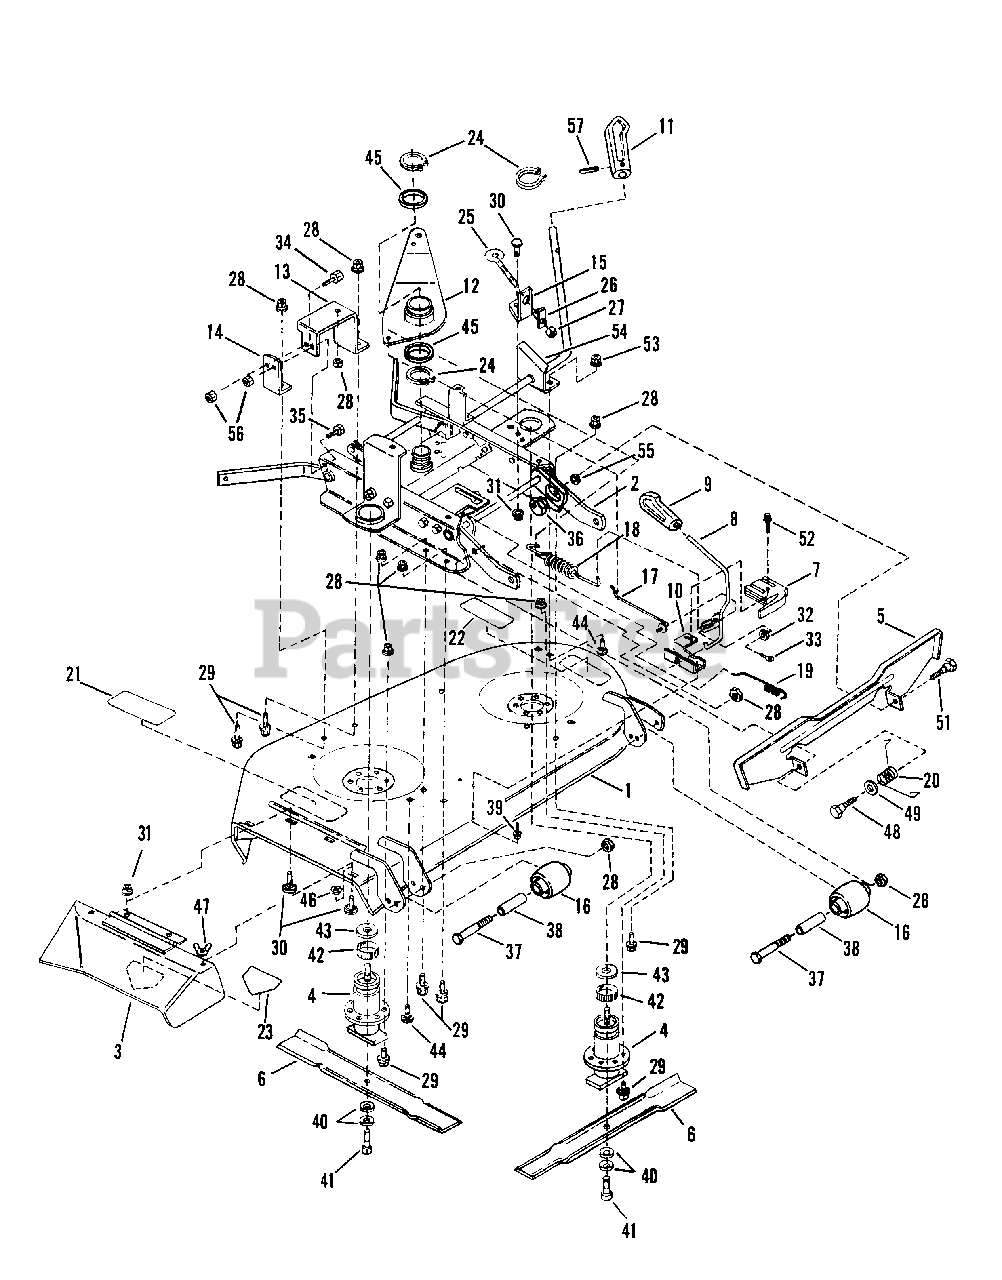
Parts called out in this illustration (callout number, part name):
1	ASSEMBLY, Deck
2	ASSEMBLY, Rail
3	ASSEMBLY, Side Chute
4	ASSEMBLY, Spindle
5	ASSEMBLY, Pedal
6	21" BLADE
7	SWITCH, Deck Interlock
8	LEVER, Blade Engagement
9	GRIP, Handle
10	MOUNT, Handle
11	GRIP, Height Adjustment Lever
12	ARM, Idler
13	SUPPORT, Idler
14	BRACKET
15	ANCHOR
16	ROLLER
17	ROD, Idler
18	SPRING, Belt
19	SPRING, Latch
20	SPRING, Pedal
21	DECAL, Caution
22	DECAL, Caution Rotating Blades
23	DECAL, Danger
24	RING, 2" External Retaining
25	BOLT, 1/4-20 Eye
26	T-NUT, 1/4-20
27	NUT, 1/4-20 Hex
28	NUT, 3/8-24 Hex Head
29	SCREW, 3/8-24 x 3/4" Hex Head Cap
30	BOLT, 5/16-18 x 3/4" Carriage
31	NUT, 5/16-18 Hex Flange Lock
32	WASHER, 1/4 Flat
33	PIN, 3/32 x 3/4" Cotter
34	SCREW, 3/8-16 x 3/4" Hex Head Cap
35	SCREW, 3/8-16 x 1" Hex Head Cap
36	ECCENTRIC, Leveling
37	SCREW, 3/8-24 x 3-3/4" Hex Head Cap
38	SPACER
39	SCREW, 1/4-20 x 5/8" Self-Tapping
40	WASHER, Cone
41	SCREW, 3/8-24 x 1" Hex Head Cap
42	RING, Tolerance
44	BOLT, 3/8-16 x 3/4" Carriage
45	WASHER, 2" I.D. Nylon
46	RETAINER, 5/16 Bolt
47	NUT, 5/16-18 Wing
48	BOLT, 3/8-24 x 9/16" Shoulder
49	WASHER, 1/2 Flat
51	BOLT, 3/8-24 x 3/4" Shoulder
52	SCREW, #10-32 x 1" Self-Tapping
53	NUT, 3/8-16 Hex Lock
54	BRACKET, Height Indicator
55	WASHER, 3/8 Internal Tooth Lock
56	NUT, 3/8-16 Hex Lock
57	PIN, 3/16 x 3/4" Roll
